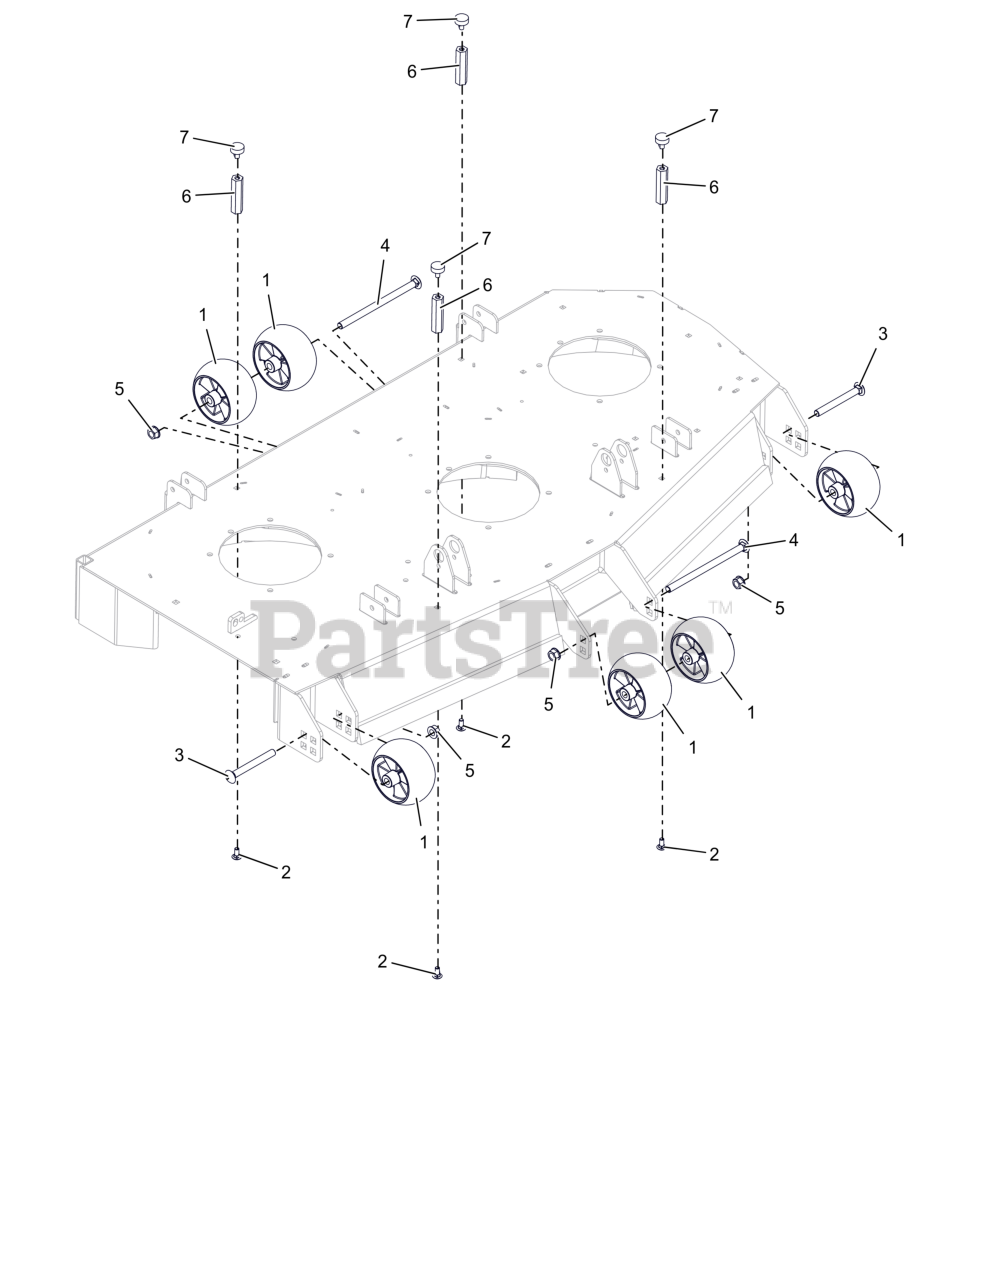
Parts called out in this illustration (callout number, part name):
1	WHEEL, ANTI SCALP - 5X3 CTR W/RIBS
2	BTL,RHSN .313-18 X 0.75 G5 ZCC LT
3	BOLT, RHNS .50-13X4.50 G5 ZCC NS
4	BOLT, RHNS .50-13X8.00 G5 ZCC NS
5	NUT-LK-CTR-FLG .500-13 GG ZCC
6	NUT, COUPLING .31-18 X 3.00
7	BUMPER, RUBBER
